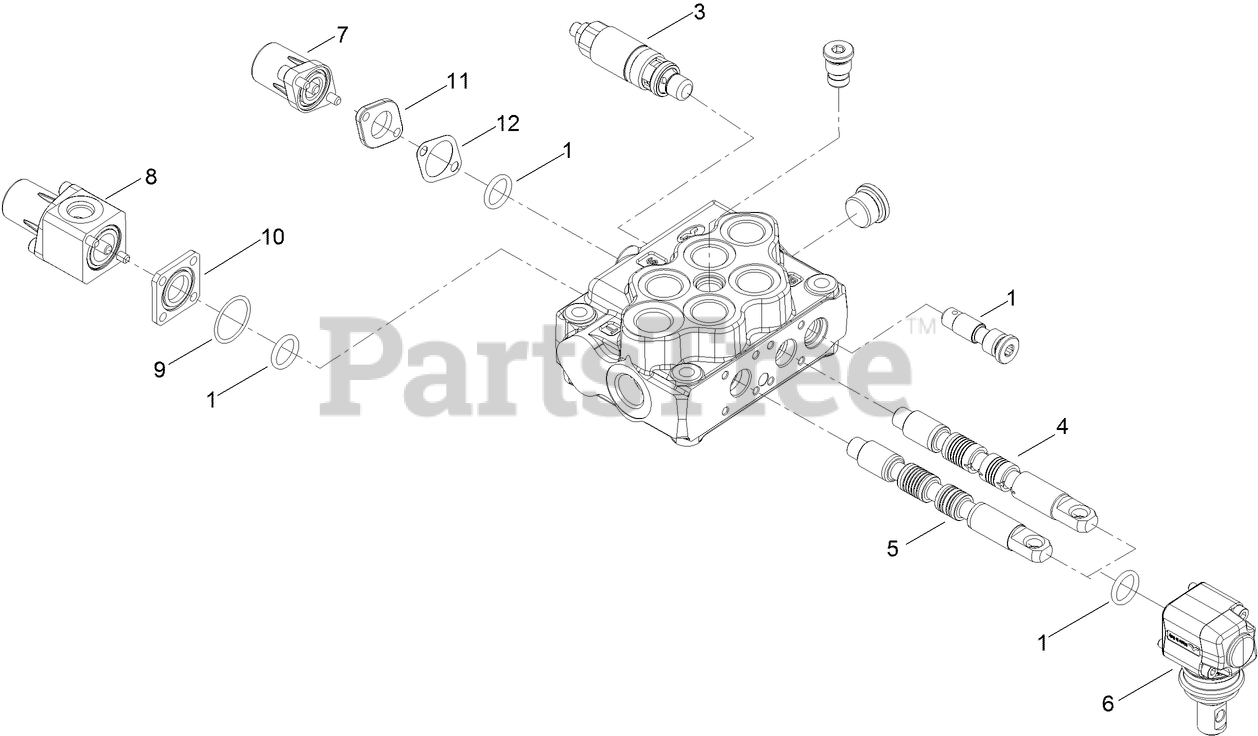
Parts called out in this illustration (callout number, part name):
1	SEAL-VALVE
3	VALVE-RELIEF
4	SPOOL-VALVE
6	LEVER KIT
7	SPRING RETURN KIT
8	SWITCH SPRING RETURN KIT
9	SEAL-RETURN
10	SPACER-SQUARE
11	SPACER-SPRING RETURN
12	GASKET-RETURN
